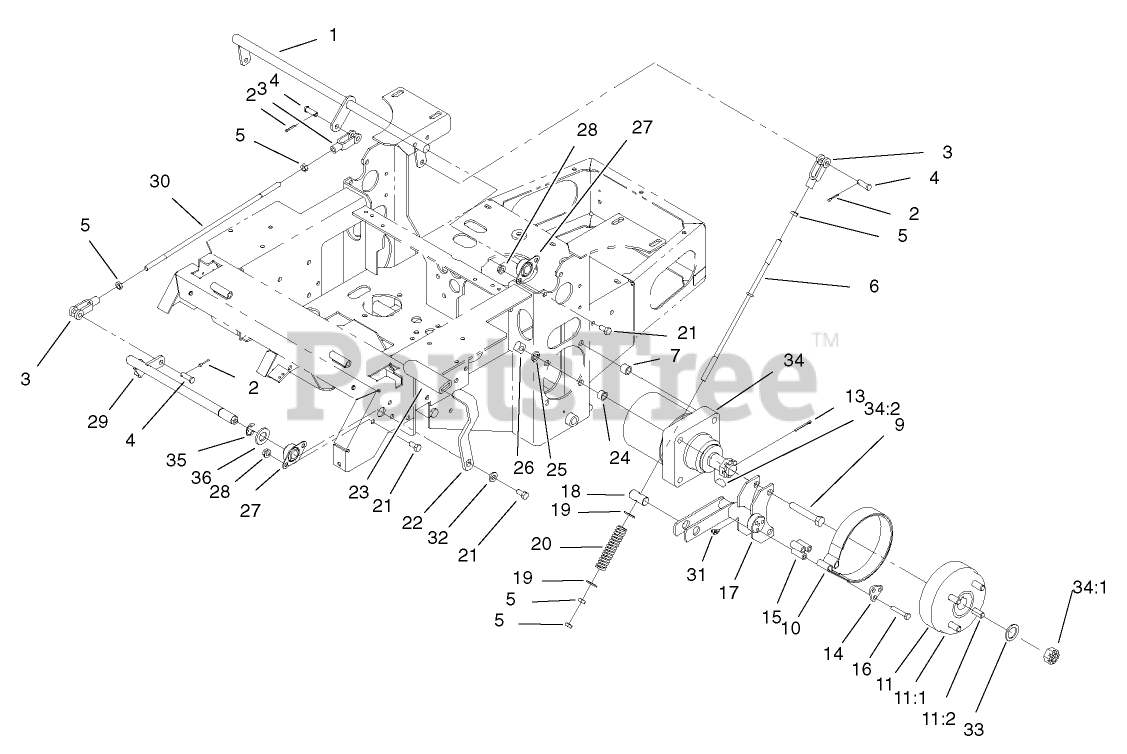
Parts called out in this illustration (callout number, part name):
1	CRANK-BRAKE, PARK
2	PIN-COTTER
3	YOKE-LINKAGE, BRAKE
4	PIN-CLEVIS
5	NUT-HEX
6	ROD-BRAKE
7	SPACER-WHEEL
9	SCREW-HH
10	BAND-BRAKE
11	WHEEL HUB ASM
11:1	HUB-WHEEL
11:2	STUD-WHEEL
13	PIN-COTTER
14	RETAINER-BAND, BRAKE
15	SPACER
16	SCREW-HH
17	BRACKET-BRAKE
18	PIN-TRUNION
19	WASHER-FLAT
20	SPRING-BRAKE
21	SCREW-HH
22	HANDLE-BRAKE, PARK
23	GRIP-LEVER
24	SPACER-WHEEL
25	WASHER-LOCK
26	NUT-SQUARE
27	BEARING-FLANGE, SIDE
28	NUT-HHF, WHIZ
29	SHAFT-BRAKE, PARKING
30	LINKAGE-HANDLE, BRAKE
31	FITTING-GREASE
32	WASHER-BELLEVILLE
33	WASHER-SPACER
34	MOTOR-WHEEL
34:1	NUT-HH
34:2	KEY-WOODRUFF
35	E-RING
36	WASHER-FLAT
